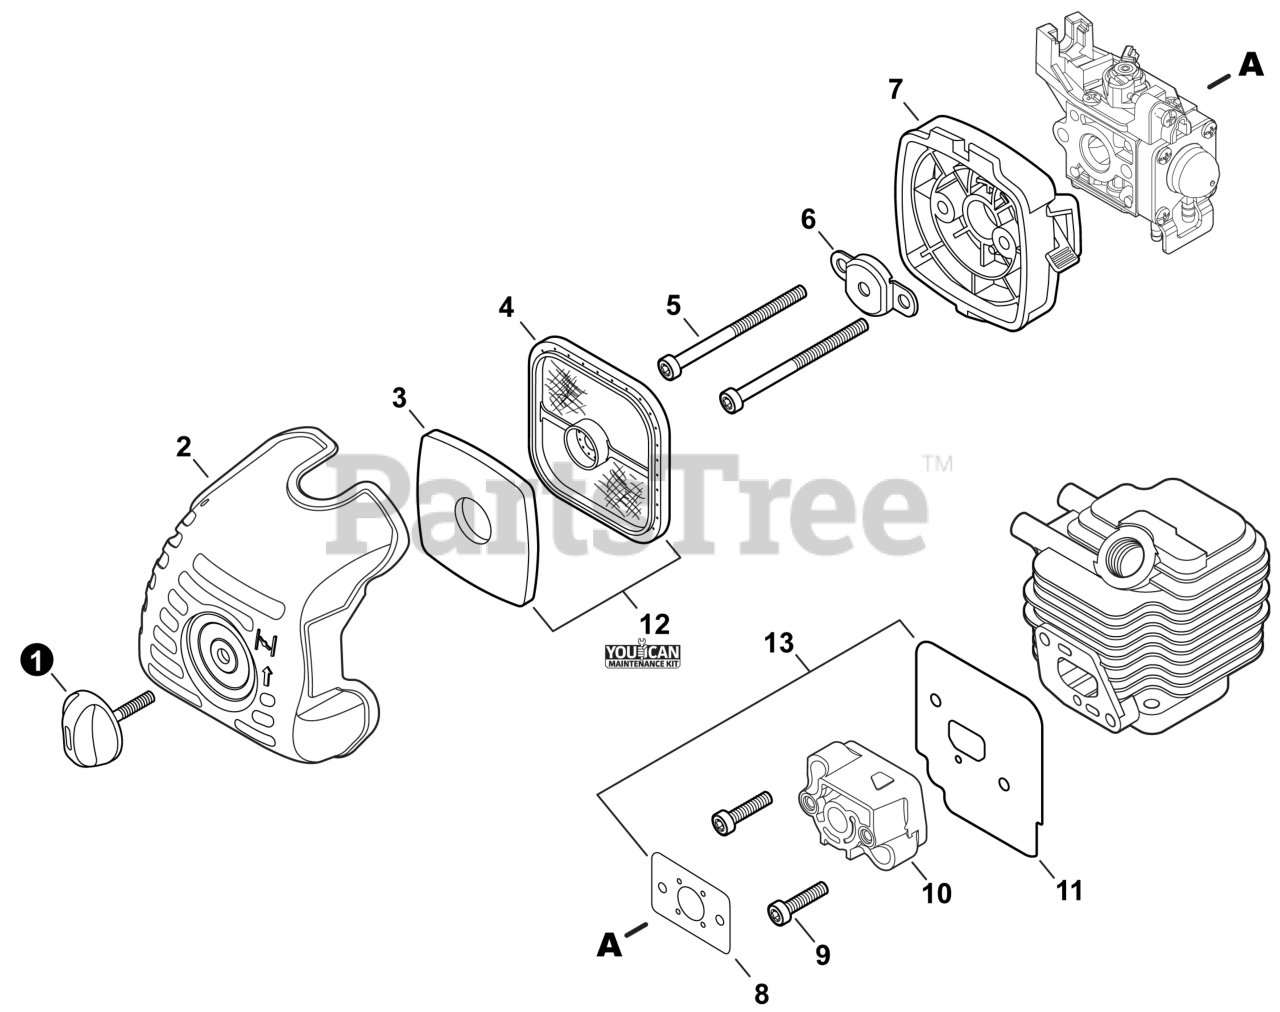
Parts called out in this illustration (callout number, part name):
1	THUMBSCREW
2	COVER, AIR FILTER
3	PRE-FILTER, FOAM
4	FILTER, AIR - DOUBLE LAYER
5	BOLT, TORX 5x55
6	PLATE, PREVENT
7	CASE ASSY, AIR FILTER
8	GASKET, INTAKE
9	BOLT, TORX 5x20
10	INSULATOR, INTAKE
11	HEAT SHIELD, INTAKE
12	TUNE-UP KIT - YOUCANT
13	GASKET KIT: ENGINE, INTAKE, EXHAUST
